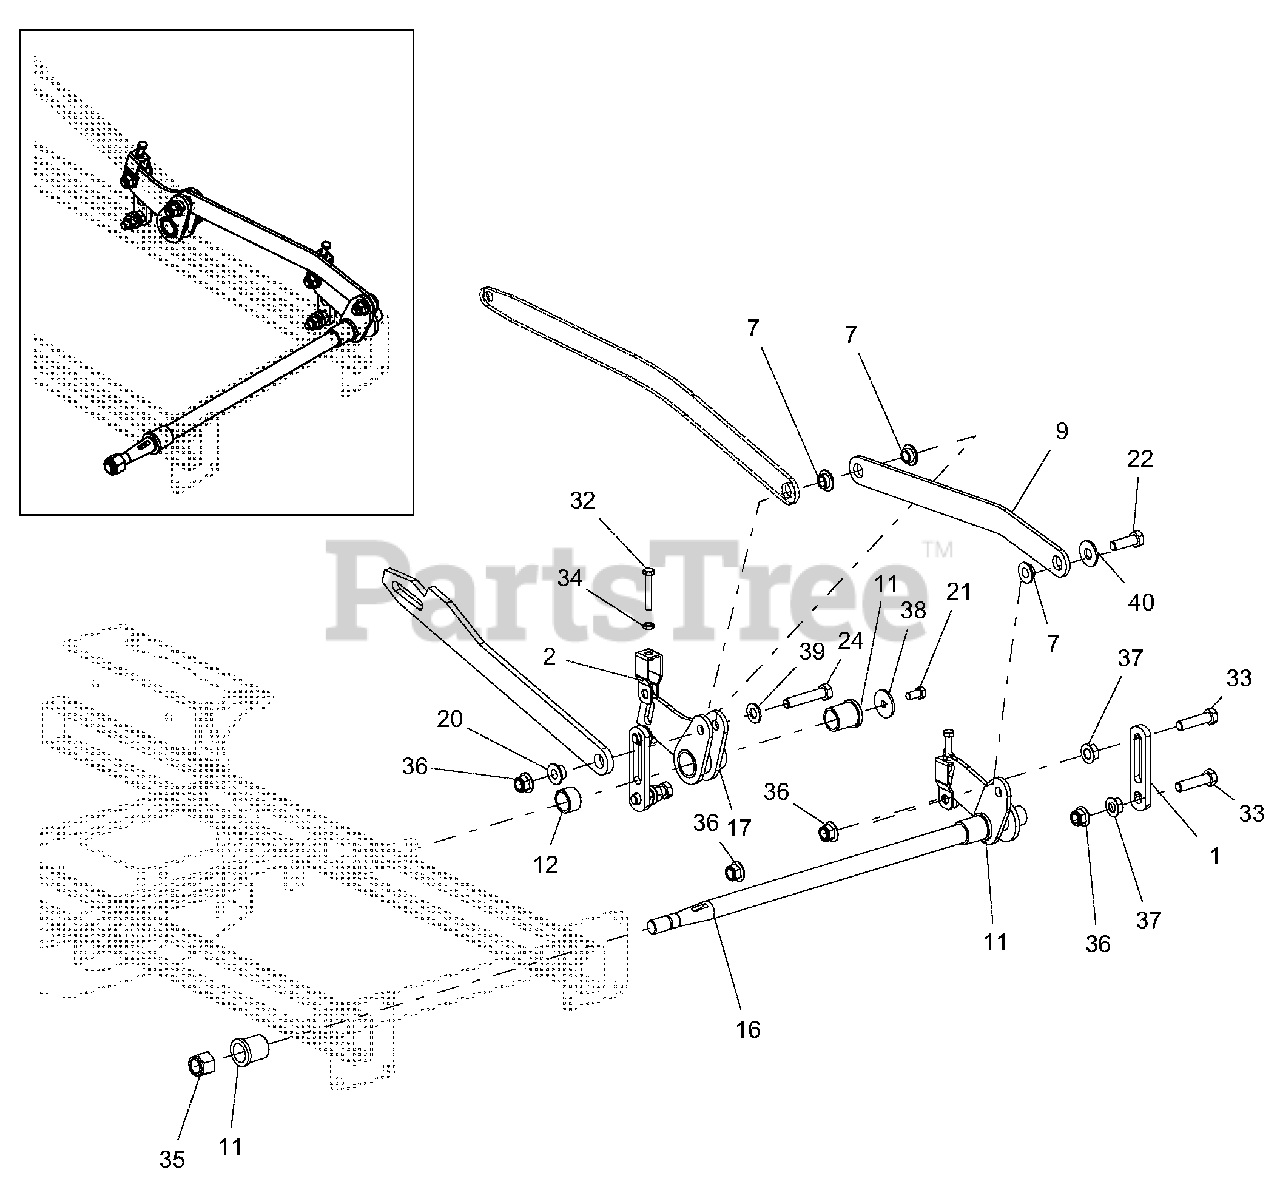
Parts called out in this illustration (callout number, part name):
1	LINK, DECK LIFT - SHORT
2	BRKT, DECK LEVELING
7	BSHG, FLANGE .515X.750X.420X1.12
9	PLATE, DECK ARM
11	BSHG-FLG 1.00X1.25X1.5X1.5
12	BSHG, 1.00 X 1.25 X .75
16	WLDMT, FRONT LH DECK LIFT ARM (BLACK)
17	WLDMT, REAR DECK ARM
20	BSHG, FLANGE .515X.750X.420X1.12
21	BLT-HEX .38-16X.75 GR5 YWZC
22	BLT-HEX .50-13X1.50 GR5 YWZC
24	BLT-HEX .50-13X2.50 GR5 YWZC
32	BLT-HEX .31-18X2.00 FTH GR5 YWZC
33	BLT-HEX .50-13X2.00 GR5 YWZC
34	NUT, JAM .312-18 YWZC
35	NUT-LK-NYL .75-10 YWZC
36	NUT-LK-NYL-FLG .50-13 YWZC
37	NUT .50-13 WIZ FLANGE
38	WSHR-FL-STL .380X1.50X.125 YWZC
39	WSHR-FL-STL.531X1.06X.095YWZC
40	WSHR-FL-STL.563X1.38X.109YWZC
